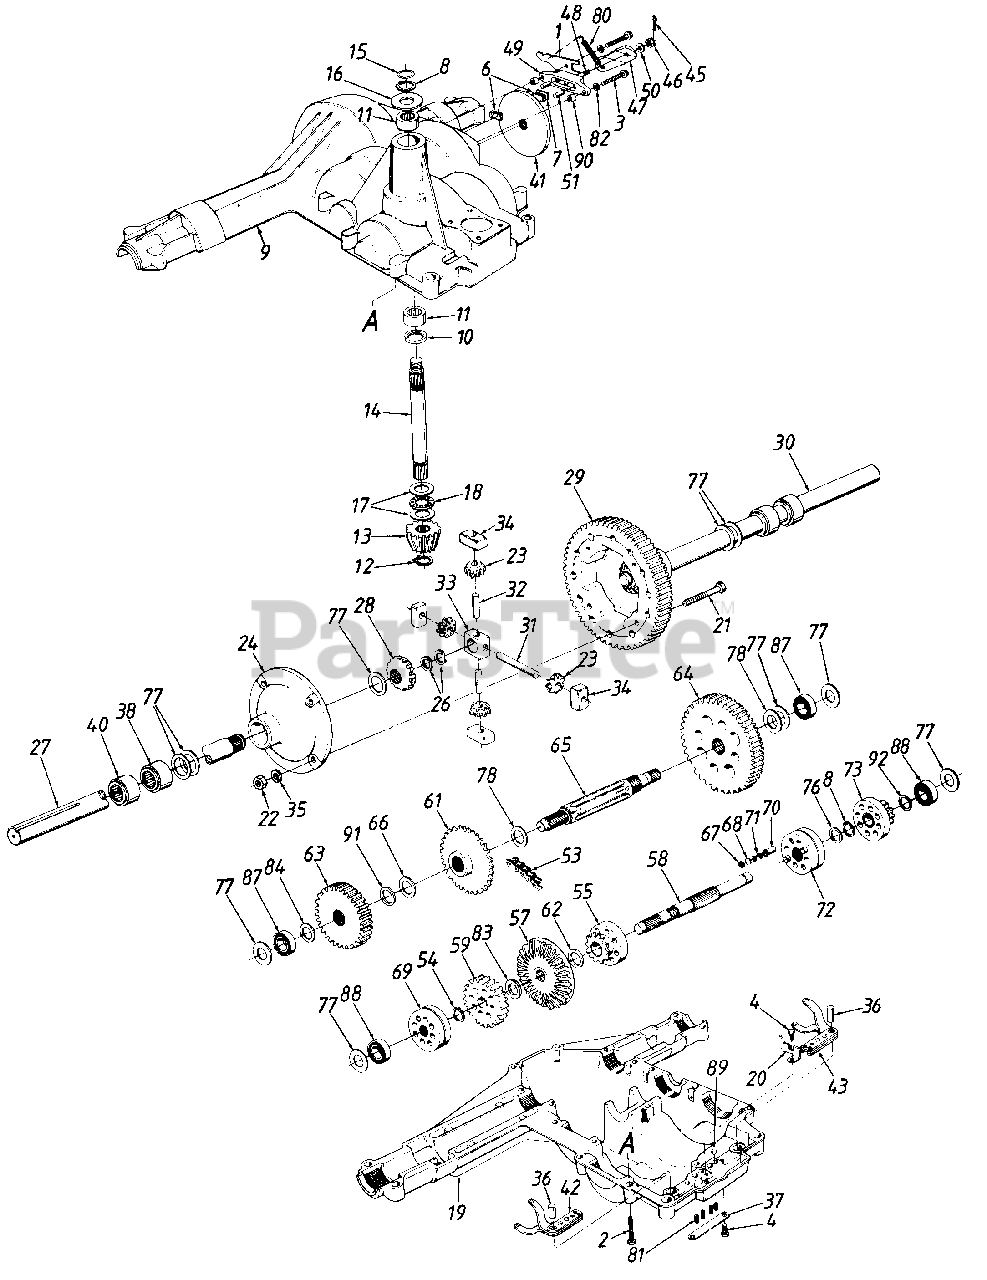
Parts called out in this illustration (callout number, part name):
1	Brake Return Bracket
2	Hex Bolt 1/4-20 x 1.25" Lg.
3	Hex Bolt 1/4-20 x 1.5" Lg. (Grade 5)
4	Tap Scr. 1/4-20 x .38" Lg.
6	Brake Puck
7	Puck Plate
8	Retainer Ring
9	Upper Housing
10	Oil Seal
11	Needle Brg. 5/8" I.D. x 7/8" O.D.
12	Snap Ring
13	Input Pinion 15T
14	Input Shaft
15	Wire Ring
16	Thrust Washer 518" I.D.
17	Thrust Washer
18	Thrust Bearing
19	Lower Housing
20	Shift Guide
21	Hex Bolt 3/8-24 x 2.0" Lg.
22	Hex L-Nut 3/8-24 Thd. (Grade 5)
23	Differential Gear 1OT
24	Differential Housing Cover Ass'y.
26	Retainer Ring
27	Axle R.H.
28	Differential Gear 14T
29	Differential Bull Gear 60T
30	Axle L.H.
31	Cross Shaft
32	Cross Shaft-Special
33	Differential Pinion Block
34	Differential Thrust Block
35	Spr. Wash. .39" I.D. x .62" O.D.
36	Shift Pin
37	Spring Plate
38	Axle Bearing Ass'y.
40	Axle Bearing Ass'y.
41	Brake Disc
42	Shift Arm Ass'y.-R.H.
43	Shift Arm Ass'y.-L.H.
45	Cotter Pin 3/32" Dia.
46	Castle Nut 5/16-24 Thd.
47	Brake Actuating Arm
48	Sq. Hd. Bolt 5/16-24 Thd.
49	Brake Yoke
50	Fl-Wash. 11/32" I.D. x 718" O.D.
51	Brake Actuating Pin
53	#420 Chain 1/2 Pitch x 28 Links
54	Retainer Ring
55	Reverse Sprocket Ass'y.
57	Bevel Gear 47T
58	Drive Shaft
59	Spur Gear Ass'y.
61	Sprocket 22T
62	Fl-Wash. .81" I.D. x 1.18" O.D.
63	Spur Gear 31T
64	Spur Gear 45T
65	Output Shaft 9T
66	Spacer
67	Internal Retainer Ring
68	Plu9.44" Dia.
69	Forward Shift Collar
70	Drive Pin
71	Drive Spring
72	Creeper Shift Collar
73	Creeper Collar Plate Ass'y.
76	Fl-Wash. .65" I.D. x .97" O.D.
77	Fl-Wash.
78	Fl-Wash. 1.0" I.D. x 1.56" O.D.
80	Ext. Spring 1.14" Lg.
81	Detent Spring
82	L-Wash. 1/4" I.D.
83	Fl-Wash. 518" I.D. x 1.0" O.D.
84	Fl-Wash. .68" x 1.12"
87	Ball Brg. .669" I.D.
88	Ball Bearing
89	Ball Detent .25" Dia.
90	Spacer .254" I.D. x .5" O.D.
91	Fl-Wash. .69" I.D. x 1.06 O.D.
92	Fl-Wash. 5/8" I.D. x 1.0" O.D. x .020" Thk.
